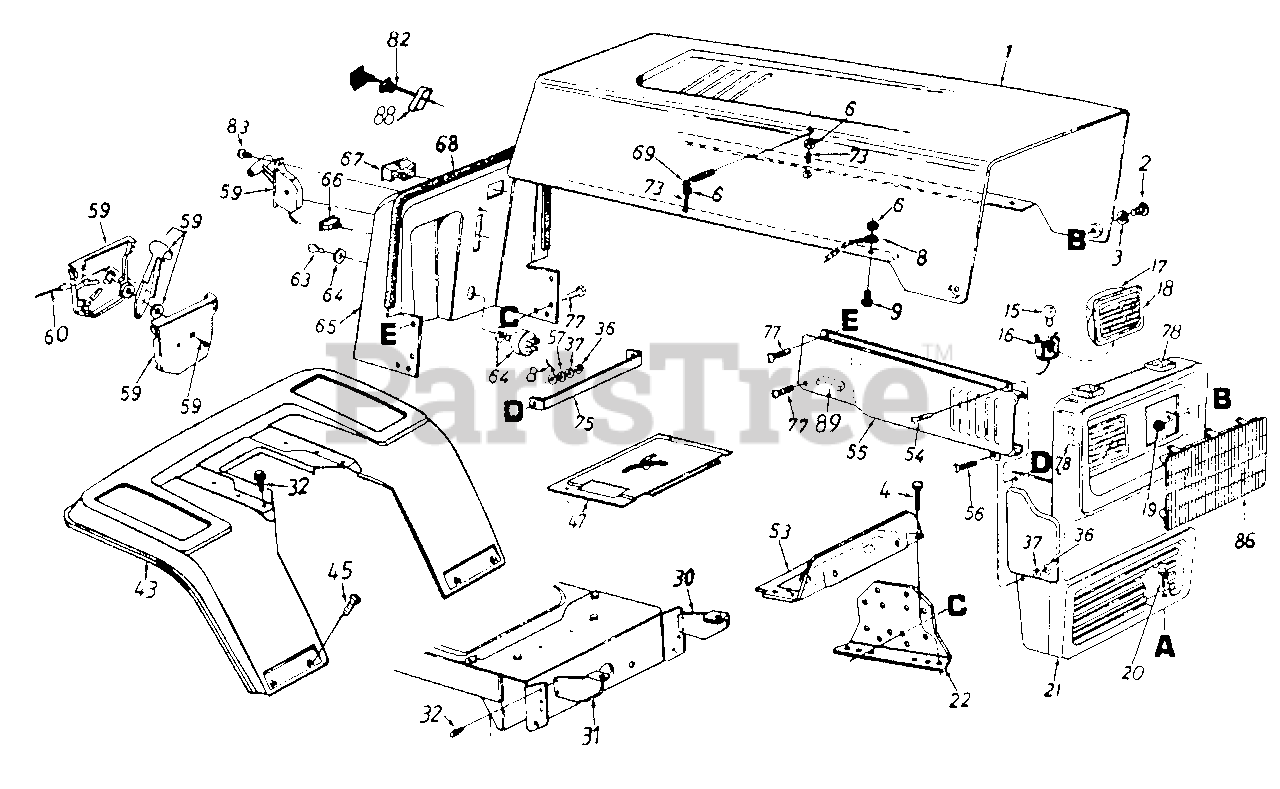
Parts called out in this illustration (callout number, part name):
3	Washer.39" I.D. x .62"
4	Hex Wash. Hd. B-Tap Scr. 5/16-18 x .5" Lg.
6	Hex Sems Nut #10-24 Thd.
8	Hood Stop
9	Truss Hd. Scr. #10-24 x 1/2"
15	Lamp
16	Twist Lock-Lamp Socket
17	Headlight Housing
18	Lens
19	L-Nut 1/4-28 Thd
20	Hex Bolt 5/16-18 x .75" Lg.
30	Grille Mount Brk't.-L.H.
36	Hex Nut 1/4-20 Thd.
37	L-Wash. 1/4" I.D.
47	Transmission Panel
53	Fuel Tank Support
54	Truss Hd. Scr. 1/4-20 x .75"
57	Fl-Wash. .281" I.D. x .73" O.D.
59	Throttle Control Box Ass'y.
60	Throttle Control Wire
63	Ignition Key
64	Ignition Switch
67	Ammeter
68	Trim Strip-31"
69	Hood Spring
73	Hex Scr. #10-24 x 1.0" Lg.
75	Tie Strap-Grille/Side Panel
77	Hex Wash. Hd. Tap Scr. 1/4 x .75" Lg.
78	Foam Strip 3/8 x 1-1/8" x 1-1/2" Lg.
82	Choke Control 46" Lg.
83	Truss Mach. AB-Tap Scr. #10 x .5" Lg.
86	Headlight Bezel
88	Choke Retainer
89	Rubber Strip
17870-0498	FENDER-RR W/FRAME - OLD CUB YELLOW (0498)
17870-0638	FENDER-RR W/FRAME - MTD/TROY-BILT RED (0638)
17870-0667	FENDER-RR W/FRAME - MIDNIGHT BLUE (0667)
